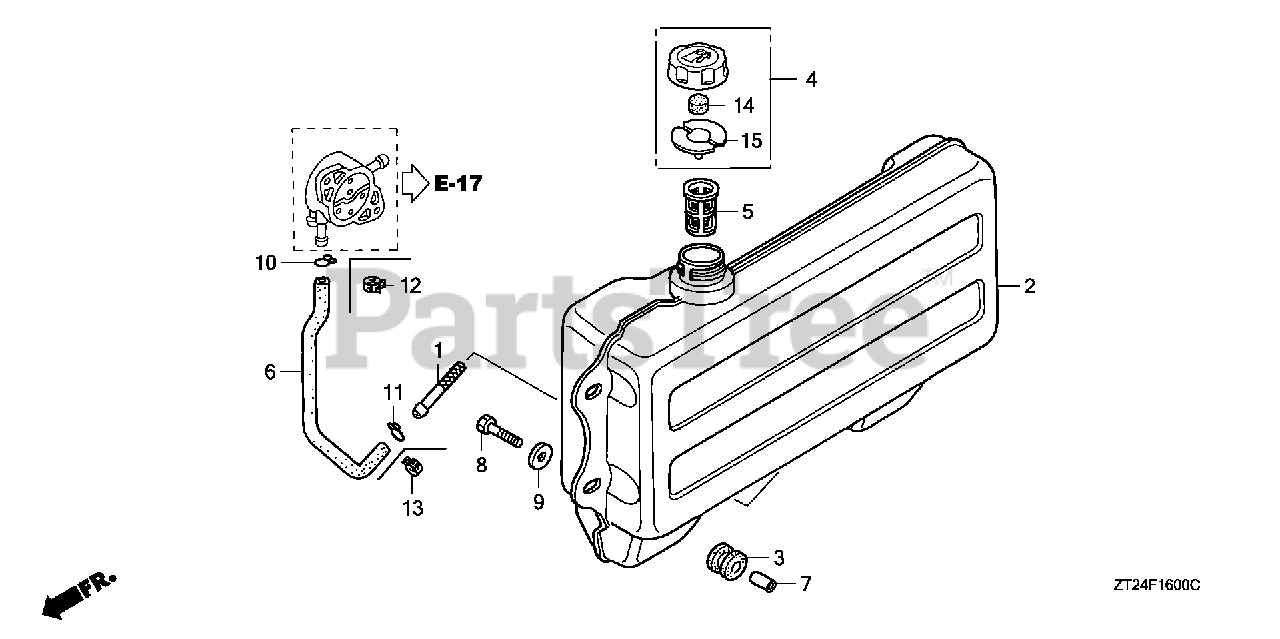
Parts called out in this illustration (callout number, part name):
1	FILTER, FUEL
2	TANK, FUEL
3	RUBBER B, TANK MOUNTING
4	CAP ASSY., FUEL TANK
5	FILTER, FUEL
6	TUBE, FUEL TANK
6	TUBE, FUEL TANK (FKM)
7	COLLAR (14X6.1)
8	BOLT, HEX. (6X25)
9	WASHER, PLAIN (6MM)
10	CLIP, TUBE (B10)
11	CLIP, TUBE (C11)
12	CLAMP, TUBE (D10.5)
13	CLAMP, TUBE (D12)
14	SPONGE, FUEL CAP BREATHER
15	GASKET, FUEL CAP
